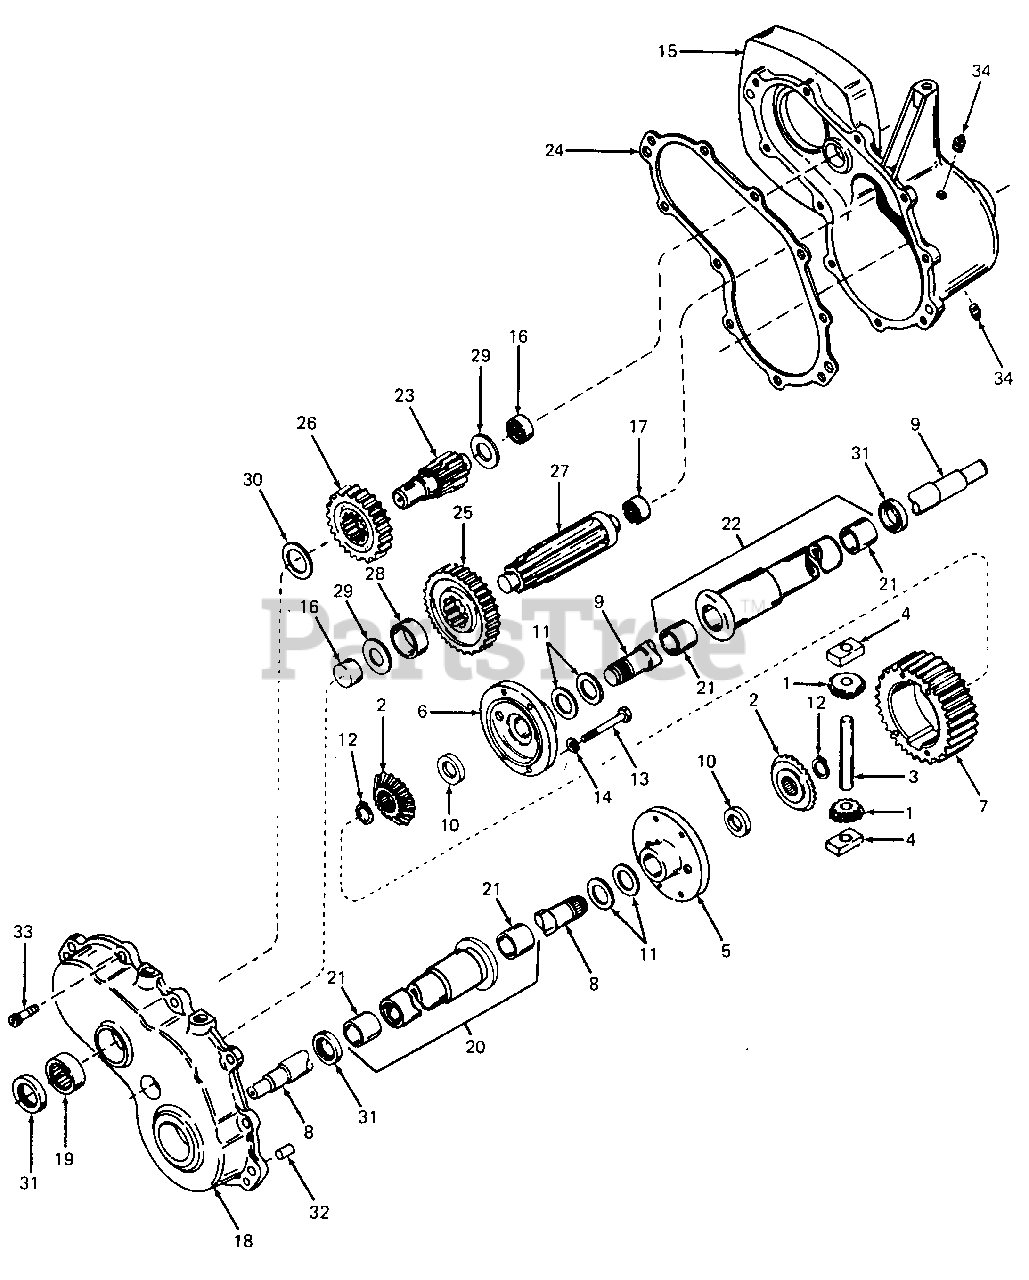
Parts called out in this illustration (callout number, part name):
1	Gear, Bevel Pinion
2	Gear, Bevel
3	Pin, Drive
4	Block, Drive
5	Carrier, Differential
6	Carrier, Differential
8	Axle, 13-5/32 Long
9	Axle, 16-3/8 Long
11	Washer, Thrust
12	Ring, Snap
13	Screw, Hex Hd Cap, 1/4-20 X 2-1/4
14	Lockwasher, 1/4
15	Case Assy
16	Bearing, Needle
17	Bearing, Needle
18	Cover Assy
19	Bearing, Needle
20	Housing & Bushing Assy, 6-5/8 Long
22	Housing & Bushing Assy, 8-5/8 Long
23	Shaft, Brake
24	Gasket, Case-to-Cover
25	Gear, Output
26	Gear, Idler
27	Shaft, Output
32	Pin, Dowel
33	Screw, Hex Hd Self-Tapping, 1/4-20 X 1
34	Plug, Pipe
